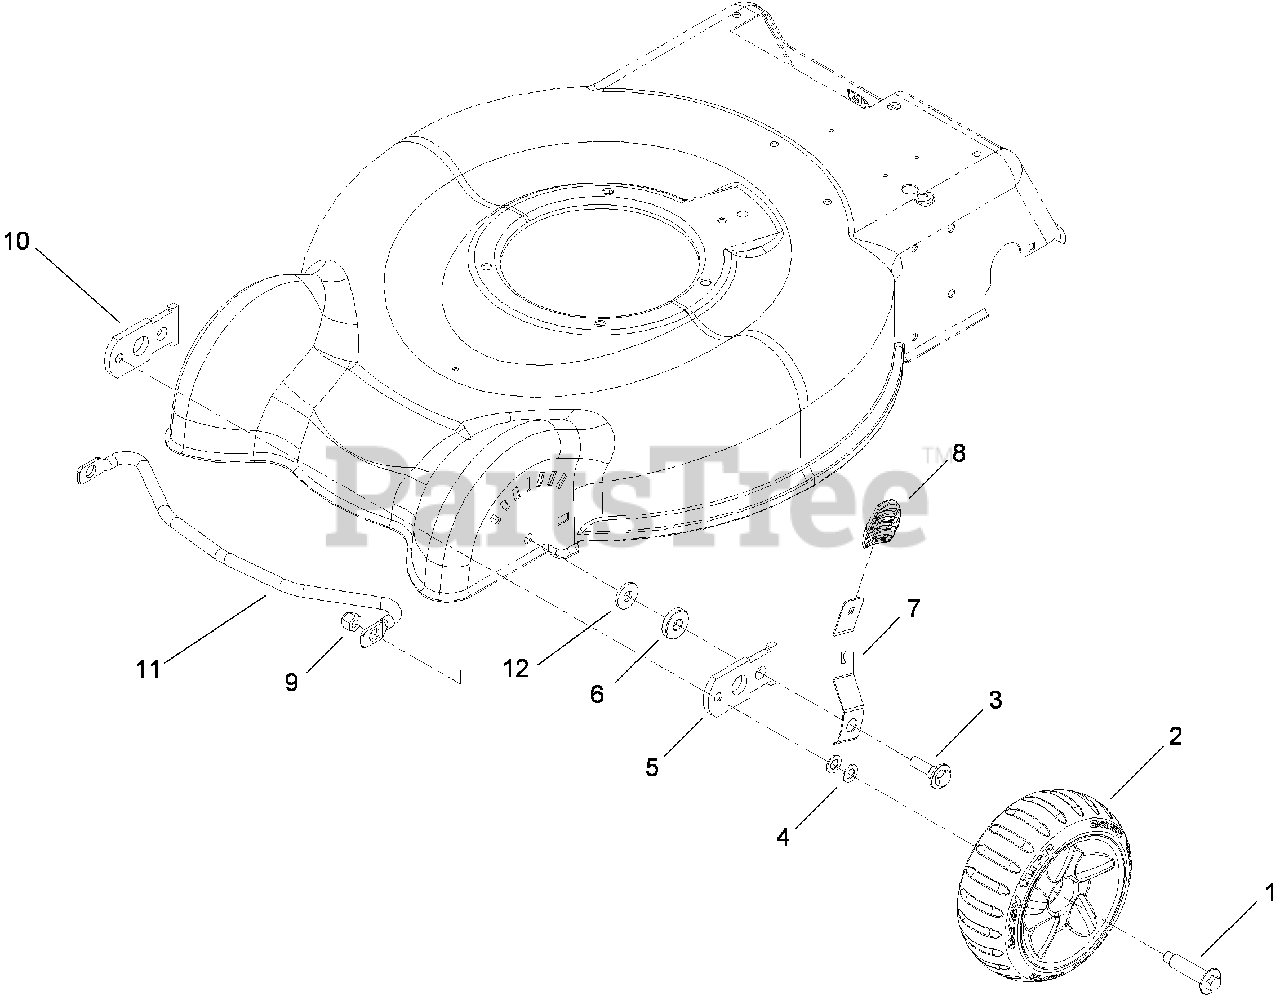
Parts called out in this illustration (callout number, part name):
1	BOLT-SHOULDER
2	7 INCH FRONT WHEEL ASM
3	BOLT-SHOULDER
5	ARM-PIVOT, RH
7	ARM-SPRING, FRONT
8	Knob-Lever, HOC
9	NUT-LOCK, NI
10	ARM-PIVOT, LH
11	BRACE-FRONT
12	WASHER-HARDENED
